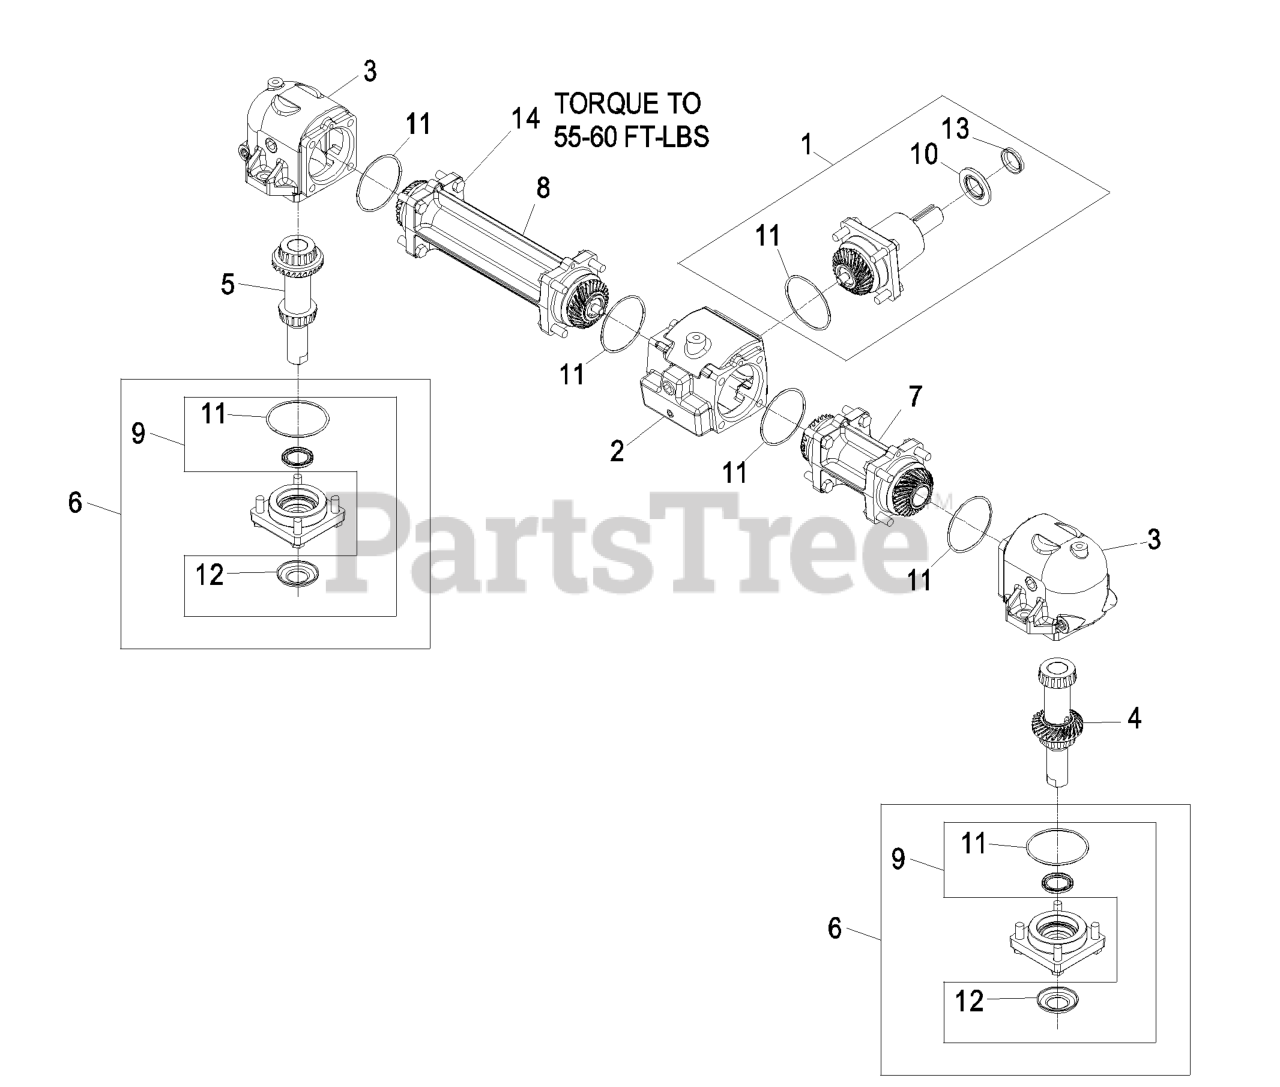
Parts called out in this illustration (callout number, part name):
1	INPUT PINION ASM
2	HOUSING-CENTER
3	HOUSING-END
4	LH OUTPUT SHAFT AND GEAR
5	RH OUTPUT SHAFT AND GEAR
6	CAP-OUTPUT
7	TUBE-CONNECTOR, SHORT
8	TUBE-CONNECTOR, LONG
9	OUTPUT SEAL KIT
10	SEAL-INPUT
11	SEAL-O-RING
12	WASHER-CUPPED
13	SEAL-V-RING
